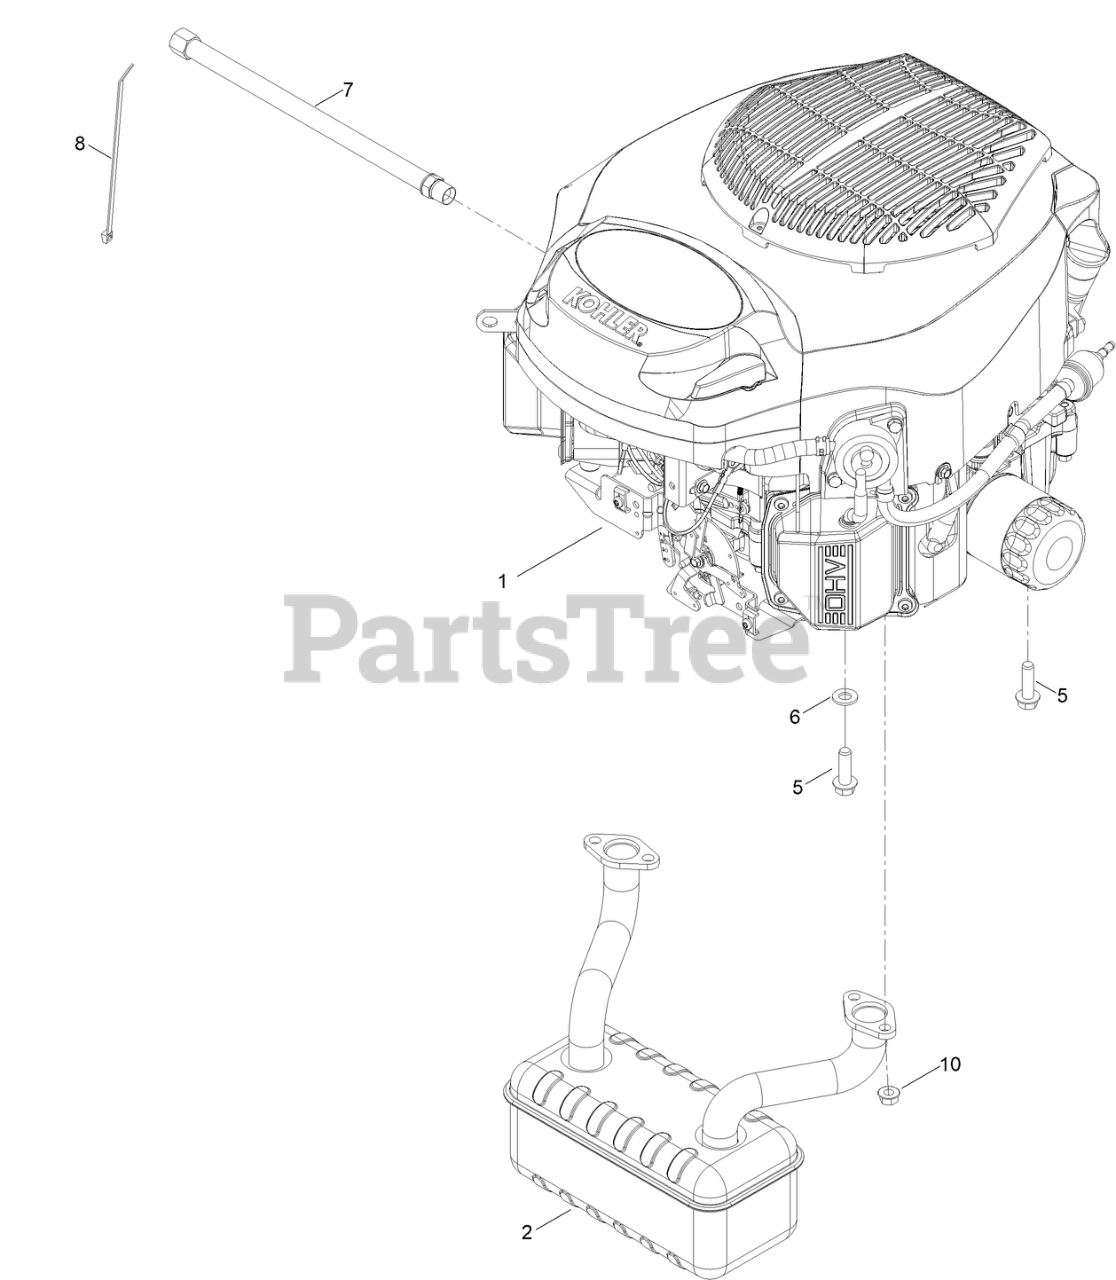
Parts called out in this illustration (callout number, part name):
1	ENGINE-KOHLER 24HP 7000 SERIES MAN CHOKE
2	MUFFLER
5	SCREW-THD
6	WASHER-FLAT
7	HOSE-DRAIN, OIL
8	TIE-CABLE
10	NUT-HF
